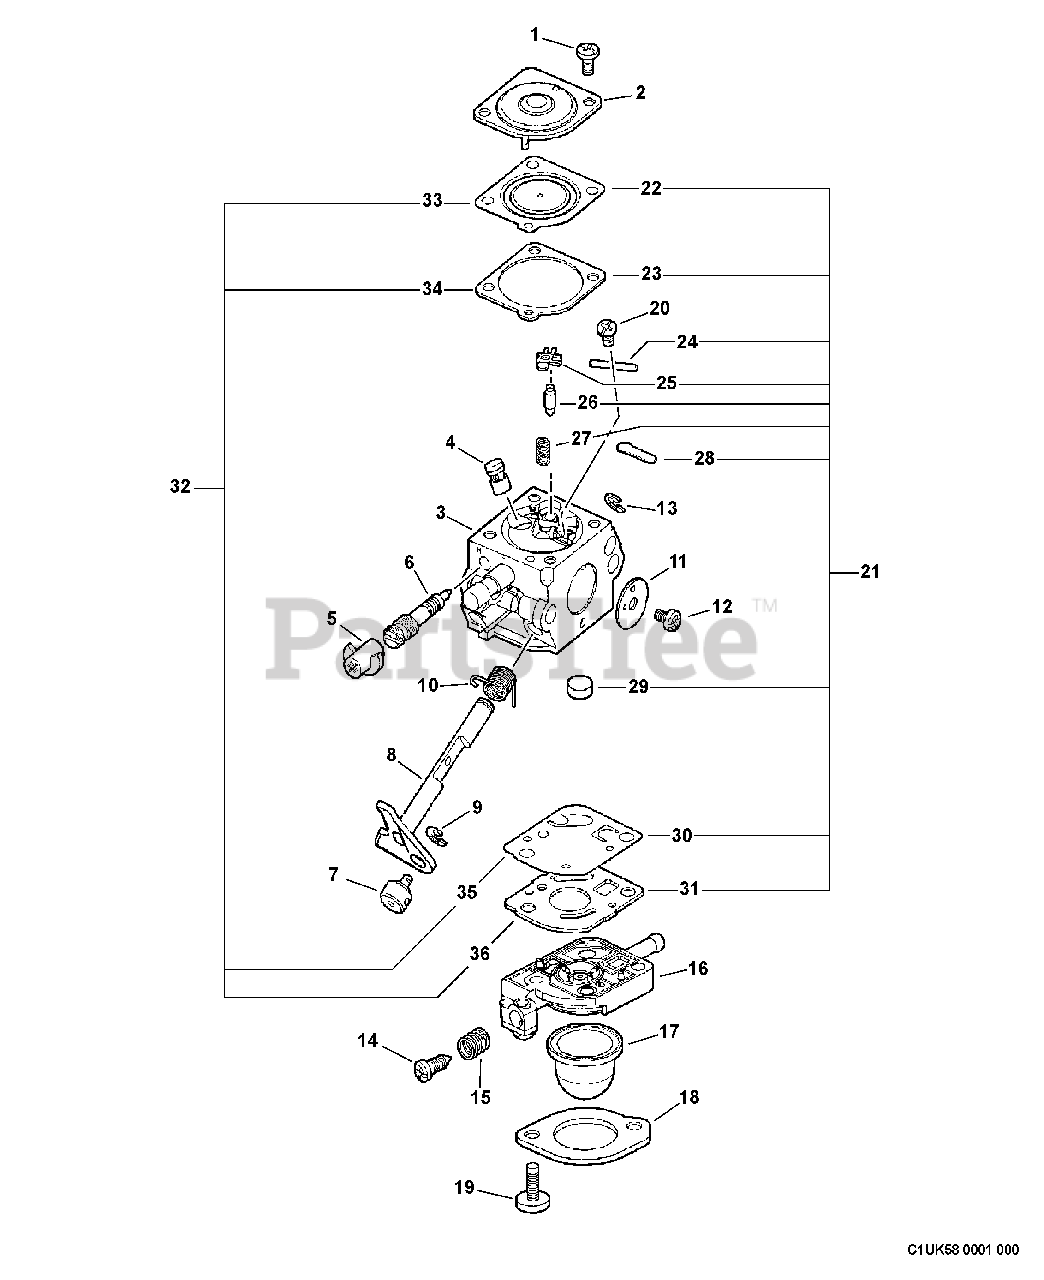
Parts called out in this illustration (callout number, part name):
2	COVER, METERING DIAPHRAGM
3	BODY, CARBURETOR
4	NOZZLE, CHECK VALVE
5	CAP, LIMITER
6	NEEDLE, HIGH SPEED
8	SHAFT, THROTTLE
10	SPRING, THROTTLE RETURN
11	VALVE, THROTTLE
14	SCREW, THROTTLE ADJUST
16	BODY ASSY, PURGE
17	BULB, PURGE
18	RETAINER
21	REPAIR KIT
22	DIAPHRAGM, METERING
23	GASKET, DIAPHRAGM
24	PIN, METERING LEVER
25	LEVER, METERING
26	VALVE, INLET NEEDLE
27	SPRING, METERING LEVER
28	PLUG, WELCH
29	STRAINER
30	DIAPHRAGM, PUMP
31	GASKET, PUMP
32	GASKET / DIAPHRAGM KIT
33	DIAPHRAGM, METERING
34	GASKET, DIAPHRAGM
35	DIAPHRAGM, PUMP
36	GASKET, PUMP
